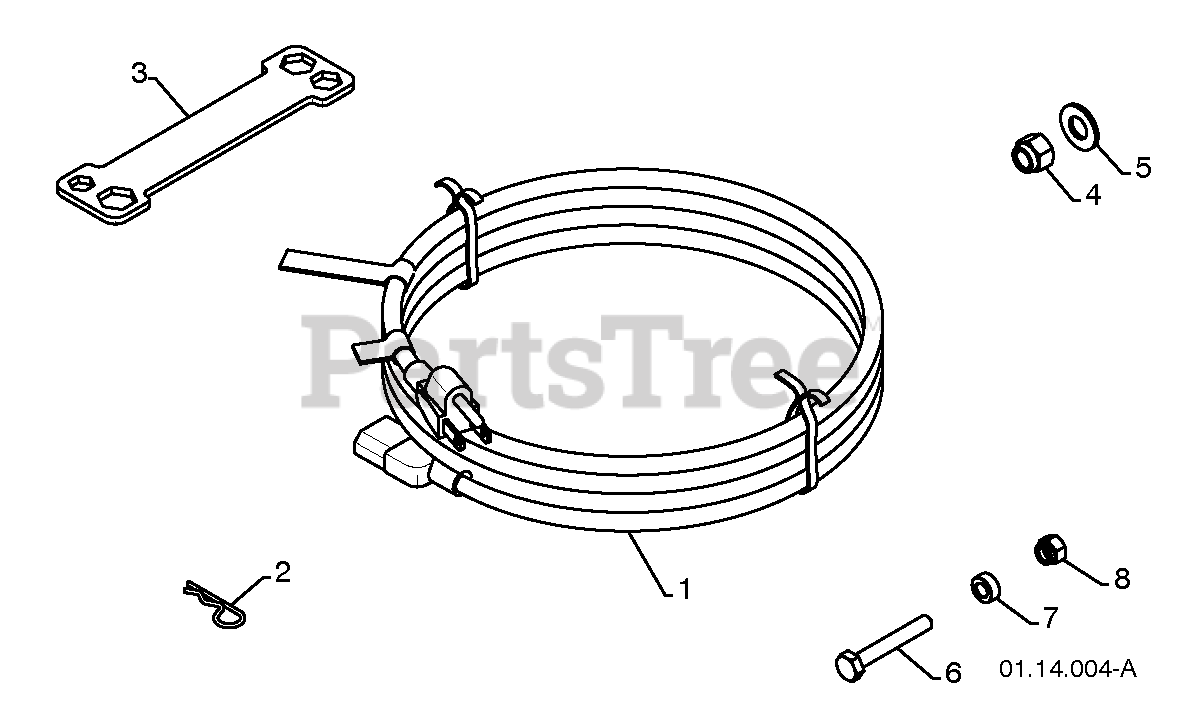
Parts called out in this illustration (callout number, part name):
1	POWER CORD
2	RETAINER PIN
3	WRENCH
4	LOCKNUT 3/8-16
5	WASHER 3/8
6	SHEAR BOLT 1/4-20 X 1-3/4
8	LOCKNUT 1/4-20
